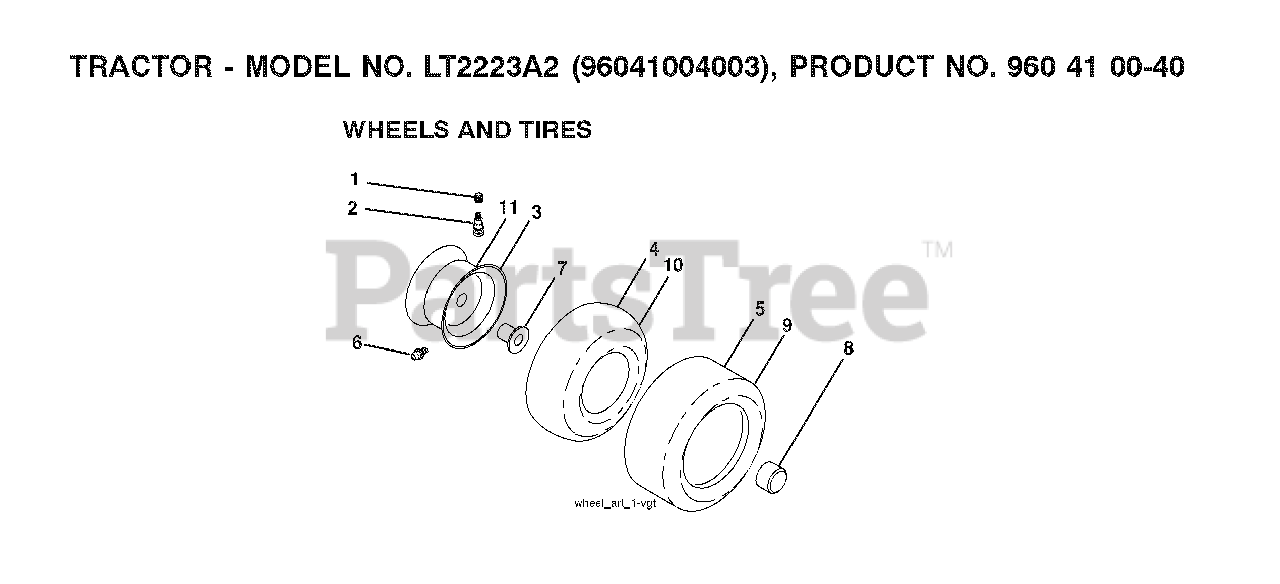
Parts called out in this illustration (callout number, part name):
1	VALVE CAP
2	VALVE STEM LT
3	RIM ASSEMBLY, FRONT
4	TUBE.16X6.5/7.5-8
5	TIRE HEAVY DUTY
6	FITTING LT
7	BEARING T
8	CAP, AXLE BLK
9	TIRE.R.TS.22 (22X9.50-12)
10	TUBE 23X950X12
11	RIM.ASM.12"REAR.SVC.417
